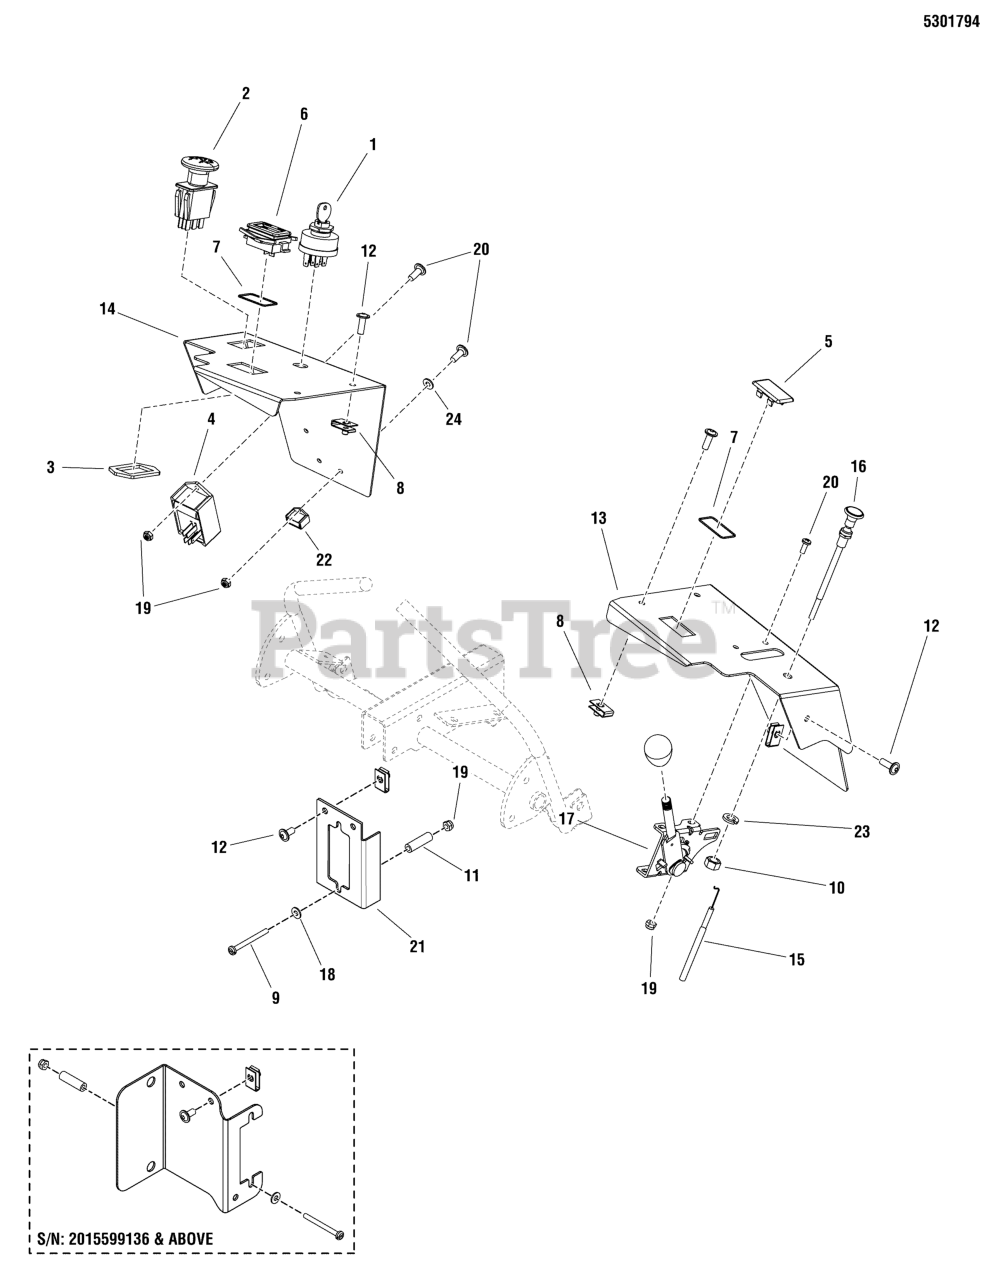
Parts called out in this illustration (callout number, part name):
1	SWITCH, IGNITION, 6 POST
2	SWITCH, BLADE ENGAGEMENT
3	RING, SWITCH RETAINER
4	MODULE, TIME DELAY
5	PLUG, .820X1.44 HOLE, BLACK PLASTIC
7	O-RING, 7/8 ID X 1/16 W
8	BODY CLIP, 1/4-20 X 1/2 DEEP
9	SCREW, #10-24 X 2 ROUND PHILLIPS
10	NUT, 3/8-24 HEX JAM
11	SPACER, .20 X .38 X 1.25
13	PLATE, CONTROL PANEL, LH - RED
14	PLATE, CONTROL PANEL, RH - RED
15	CABLE, THROTTLE, 31"
16	CABLE, CHOKE CONTROL, 35.25"
17	LEVER, THROTTLE CONTROL
18	WASHER, #10 SAE
19	NUT, #10-24 HEX NYLON LOCK
20	SCREW- #10-24 X 1/2 ROUND PHILLIPS
22	RELAY, 12V, 40A
23	WASHER, 3/8 SPLIT LOCK
